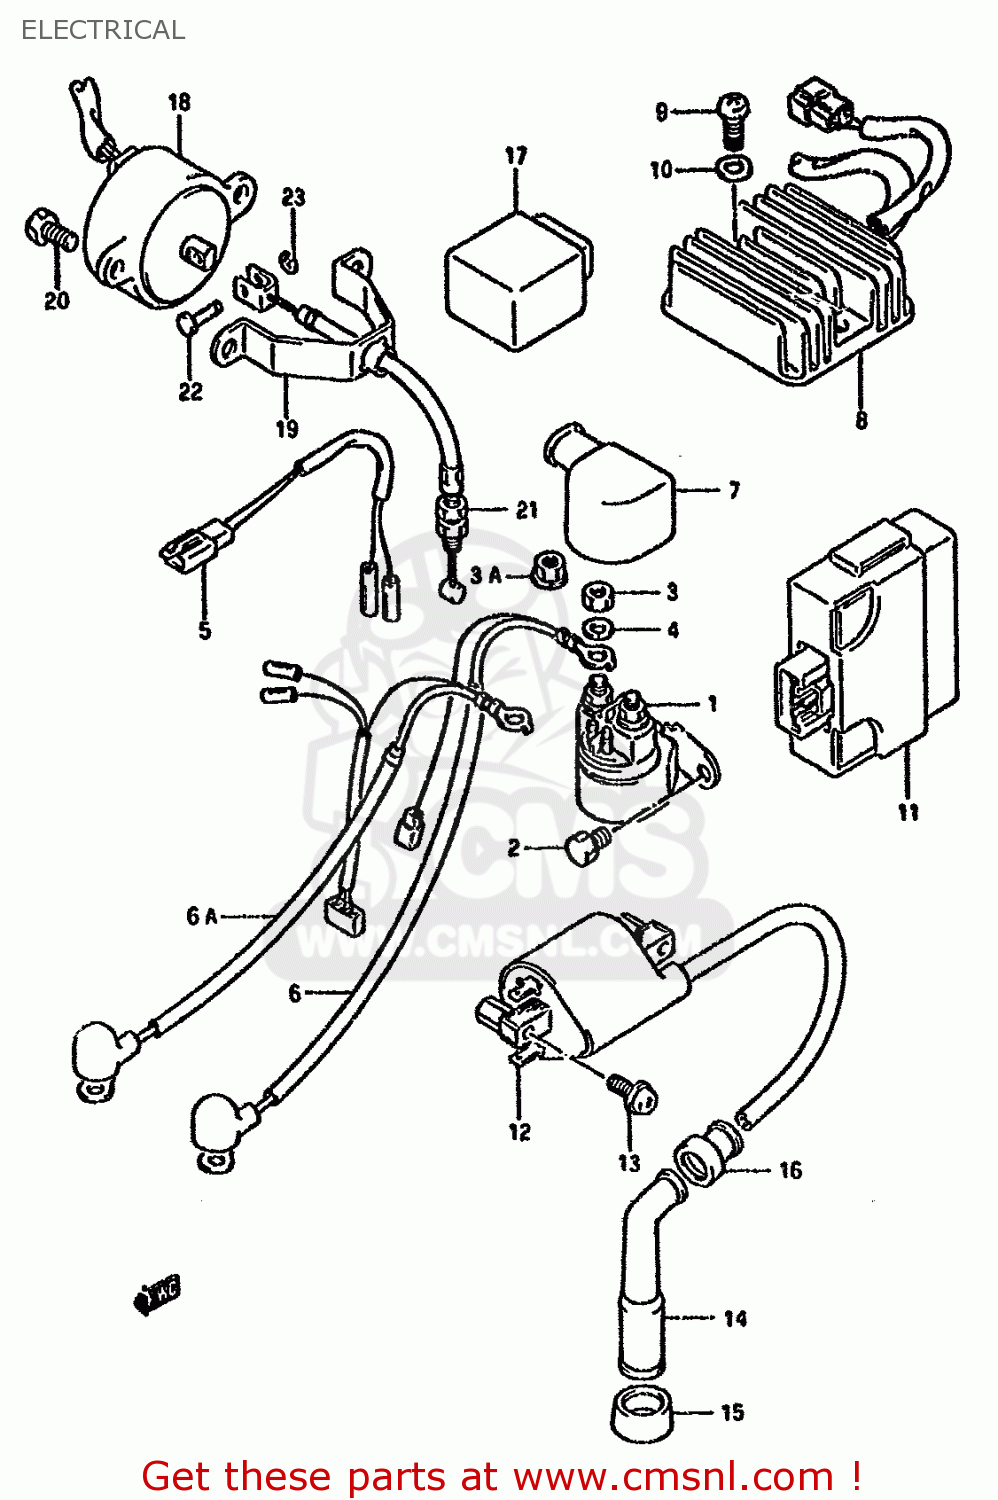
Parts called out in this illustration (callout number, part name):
1	RELAY ASSY,STARTING MOTOR
2	BOLT
3	NUT
3A	NUT
4	WASHER,LOCK
5	WIRE,STARTER RELAY LEAD
6	WIRE,STARTER MOTOR
6A	WIRE,STARTER MOTOR
7	CAP,STARTER RELAY TERMINAL
8	RECTIFIER ASSY
9	SCREW
10	WASHER, LOWER
11	IGNITOR ASSY
12	COIL ASSY,IGNITION
13	SCREW
14	CAP ASSY,SPARK PLUG
15	SEAL,SPARK PLUG CAP
16	SEAL,SPARK PLU
17	CONTROL UNIT,DECOMP
18	SOLENOID ASSY,DECOMP
19	BRACKET,DECOMP SOLENOID
20	BOLT
21	CABLE ASSEMBLY,DECOMPRESSION
22	PIN(4X12.5)
23	E RING
